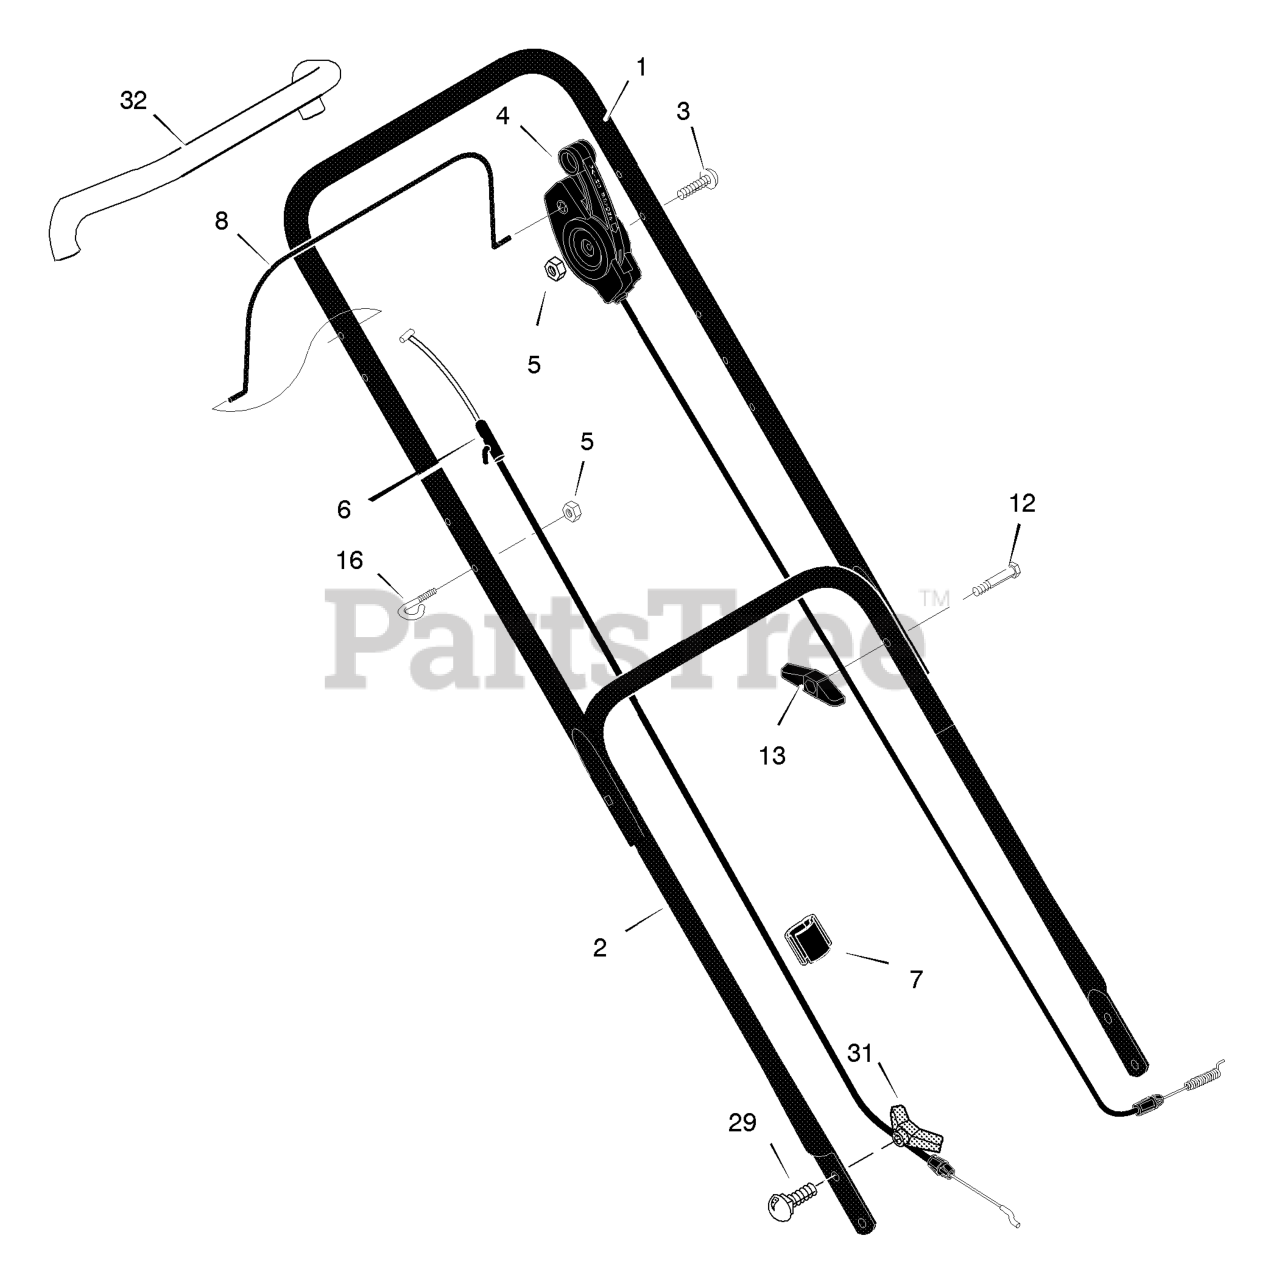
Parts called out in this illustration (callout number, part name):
1	Handle, Upper (Black)
2	Handle, Lower (Black)
4	Control, Drive
5	Locknut
6	Cable, Stop (Briggs)
7	Fastener, Double Cable
8	Lever, Stop
13	Knob
16	Guide, Rope
29	Bolt, Carriage
31	Knob, Plastic
32	Tubing, Foam
